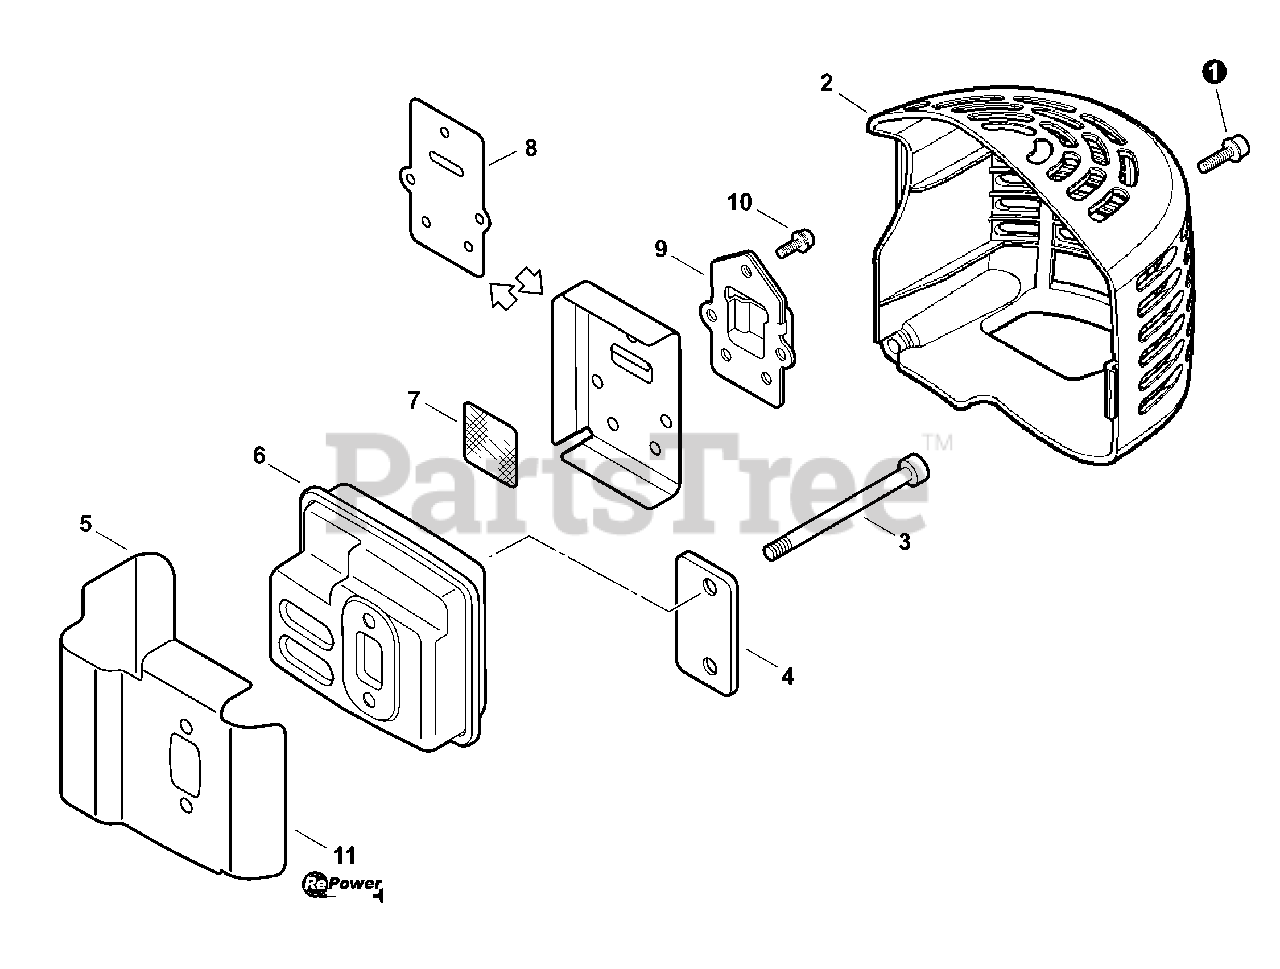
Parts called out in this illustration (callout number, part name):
1	BOLT 5×16
2	COVER, MUFFLER
3	BOLT 5×55
4	PLATE, EYE
5	HEAT SHIELD, EXHAUST
6	MUFFLER
7	SCREEN, SPARK ARRESTER
8	GASKET, EXHAUST
9	GUIDE, EXHAUST
10	SCREW 4×10
11	GASKET KIT
